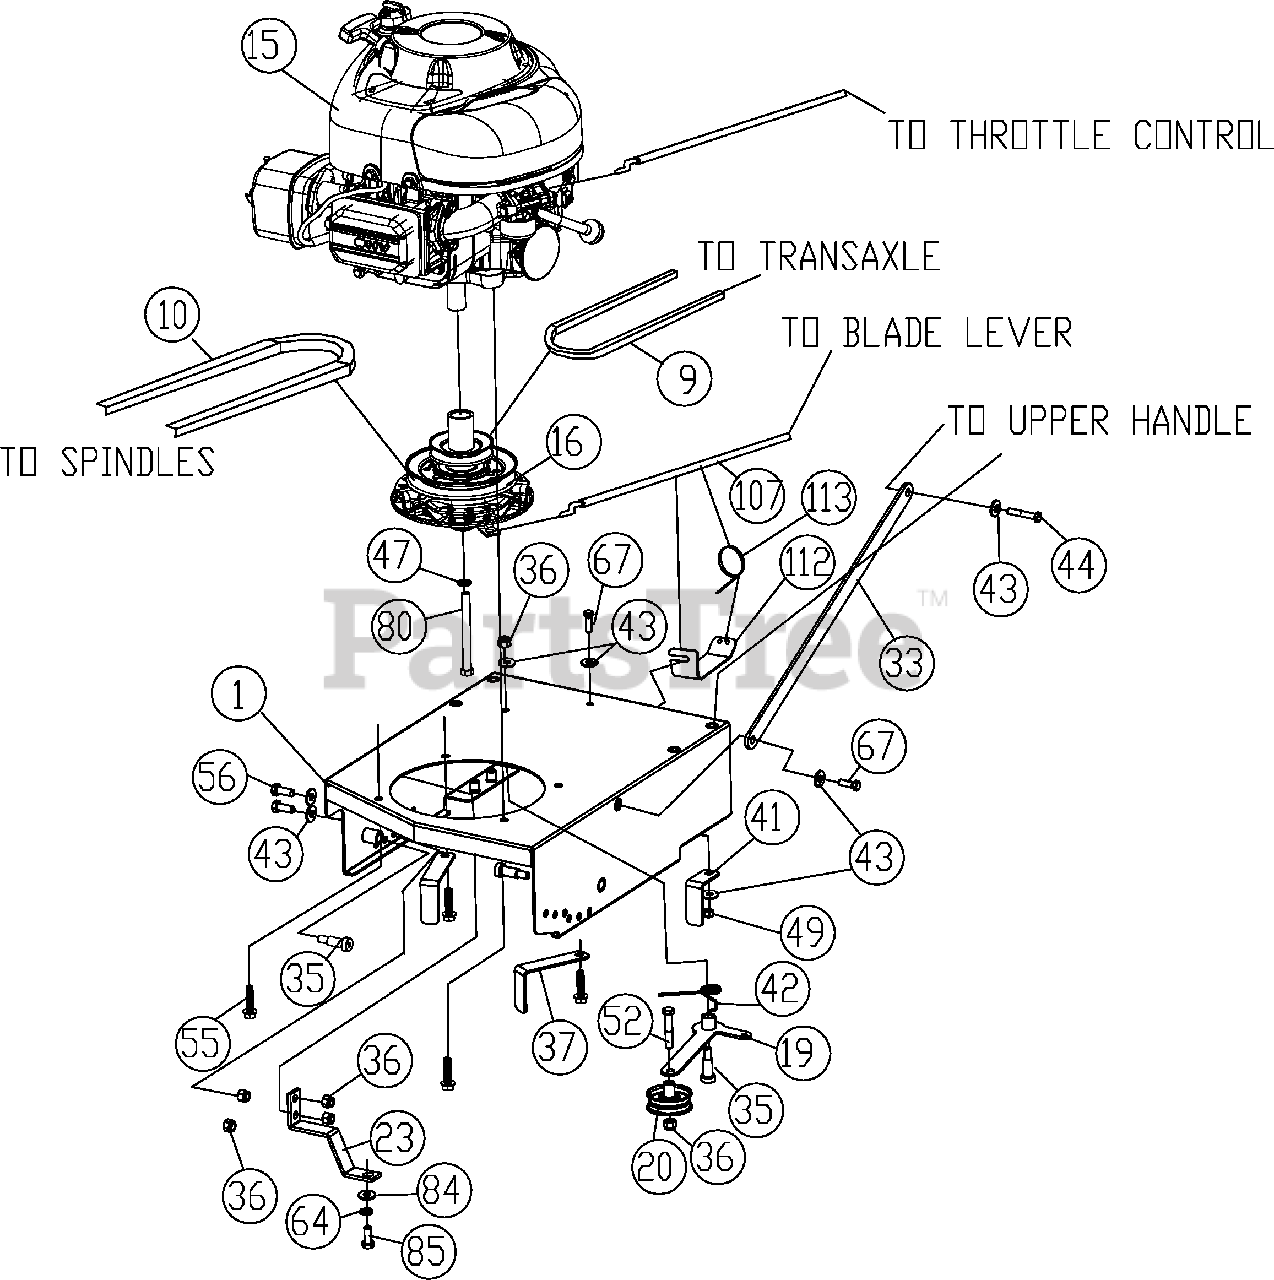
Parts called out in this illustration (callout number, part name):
1	Base Engine WA HP
9	Belt 4L x 33
10	Belt 5l x 60
15	Engine 10.5 HP Intek
16	Clutch HP
19	Idler Arm WA
20	Pulley idler arm HP
23	Bracket Anti-Rotation
33	Brace Handle HP
35	Bolt Shoulder 1/2" x 1"
36	Nut Lock 3/8" - 16
37	Belt Finger Front HP
41	Belt Finger Rear HP
42	Spring Idler HP
43	Washer 5/16 Flat ZP
44	Screwcap 5/16-18 x 1/4" HEX ZP
47	Washer lock 7/16" S/T Med
49	Nut Lock 5/16-18 HEX ZP
52	Screwcap 3/8" - 16 x 2"
55	Screw 3/8" x 1 1/2" TCS
56	Screwcap 3/8"-16 x 1" HCS ZP
64	Washer Lock 1/4" External Tooth
67	Screwcap 5/16-18 x 1" HEX ZP
80	Screwcap 7/16-20 x 4 1/2" HCS GR. 5
84	Washer 3/8 Sae
85	Screwcap 1/4" - 20 x 1/2" HCS ZP
107	Cable Clutch Blade HP
112	Cable Guard HP
